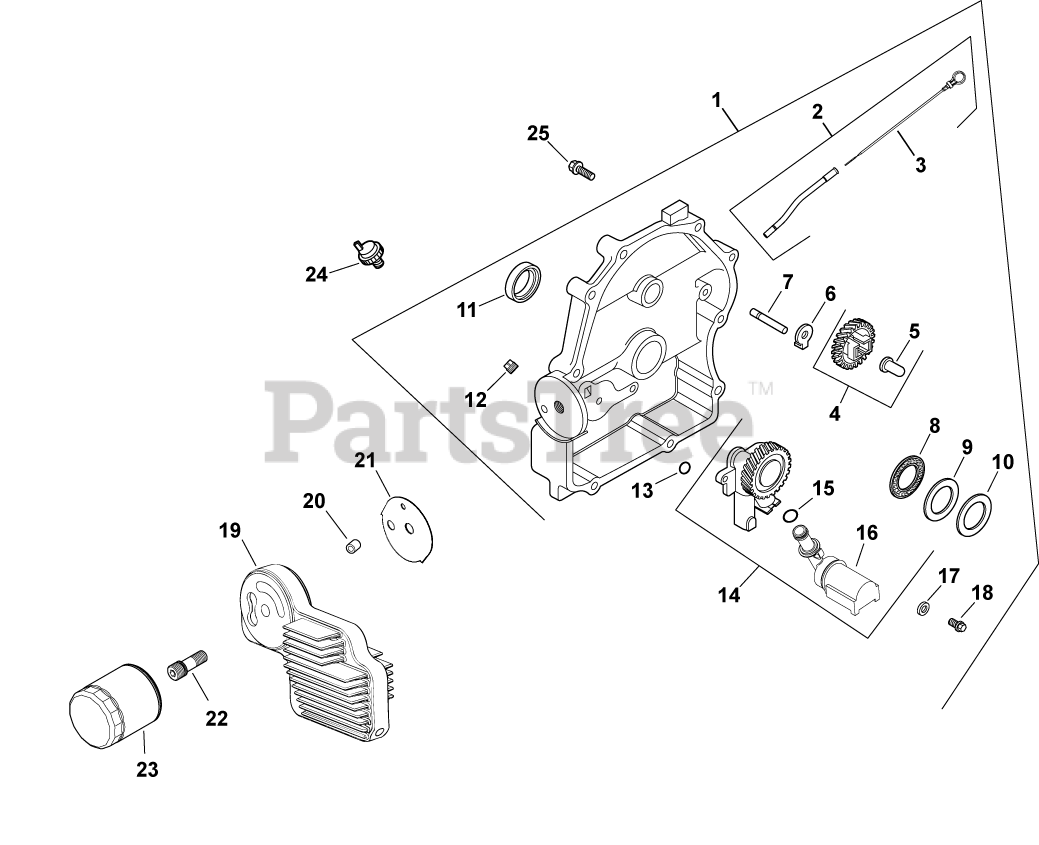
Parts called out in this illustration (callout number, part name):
1	KIT, CLOSURE PLATE USE 24 009 230-S
2	KIT, DIPSTICK/DIPSTICK TUBES
4	KIT, GOVERNOR GEAR W/PIN
5	PIN, GOVERNOR REGULATING
6	TAB, LOCKING
7	SHAFT, GOVERNOR GEAR
8	BEARING, THRUST
9	WASHER, THRUST (1MM)
10	SHIM, THRUST (BLUE .5MM)
11	SEAL, OIL
12	PLUG, CTSK PIPE 1/8"
13	O-RING, OIL PICK-UP
14	PUMP ASSEMBLY, OIL-USE 24 393 53-S
16	PICK-UP, OIL
17	WASHER, FLAT 6 MM
18	SCREW,FLG THD FRM M6X1.0X25-(#25086395S)
19	COOLER, OIL ASSEMBLY
20	PIN, DOWEL (SPLIT)-USE 24 380 16-S
21	GASKET, EXHAUST
22	NIPPLE, OIL FILTER
23	OIL FILTER
24	SENSOR, OIL PSI
25	SCREW, FLG M8X1.25X45
2442205-S	SHIM, THRUST (BLACK .686MM)
